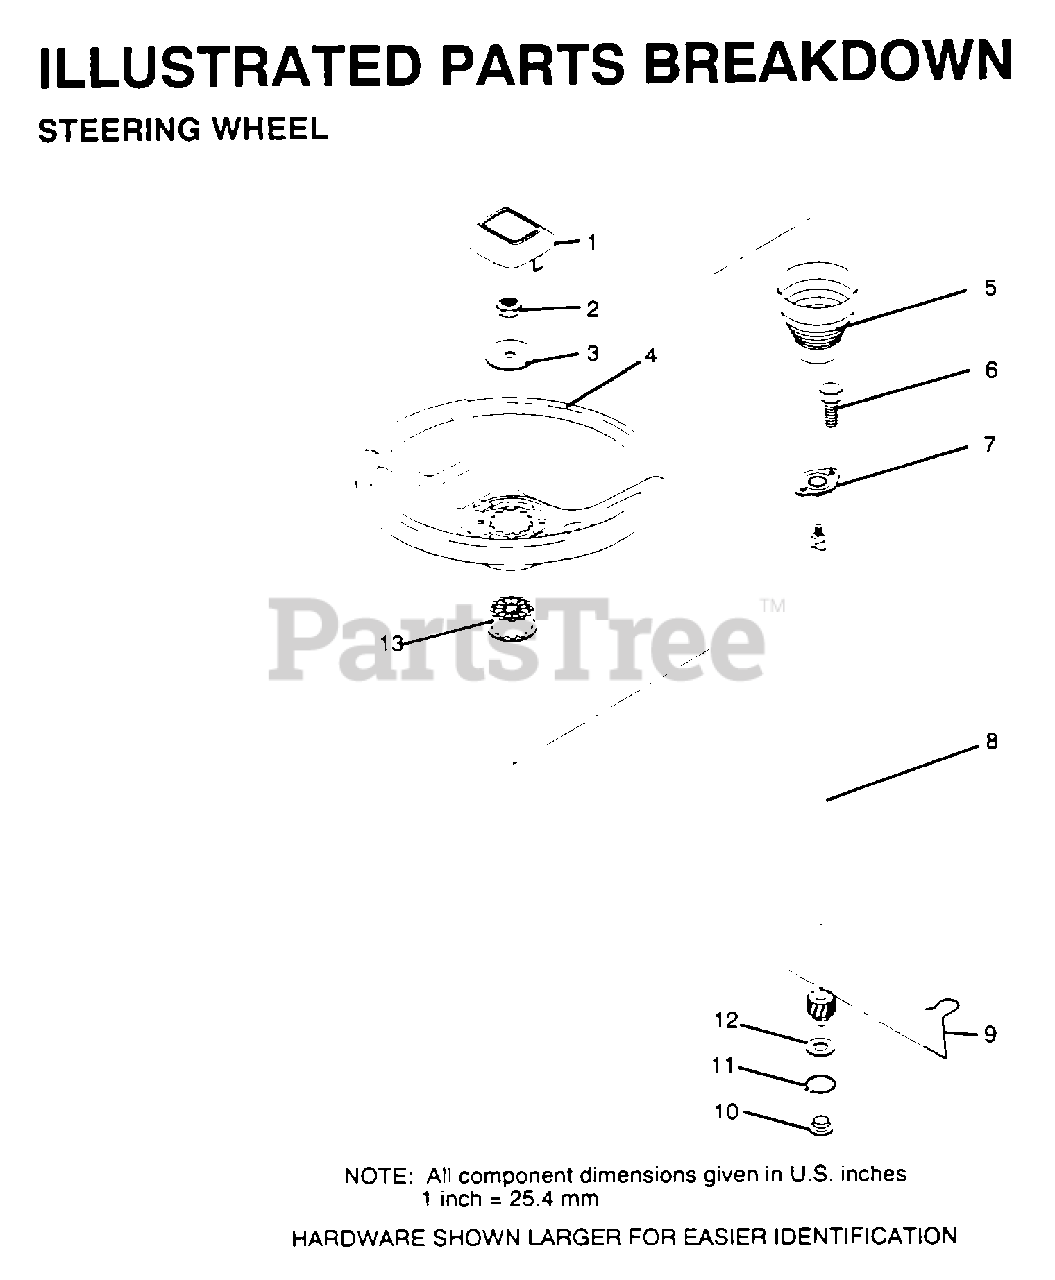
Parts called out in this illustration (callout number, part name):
1	INSERT-WHEEL LT
2	GRIPCO NUT
3	WASHER T
5	SLEEVE STEERING
9	STEERING CLIP
10	BUSHING STEER LWR
11	RING
12	WASHER LT
13	ADAPTER-WHEEL LT
